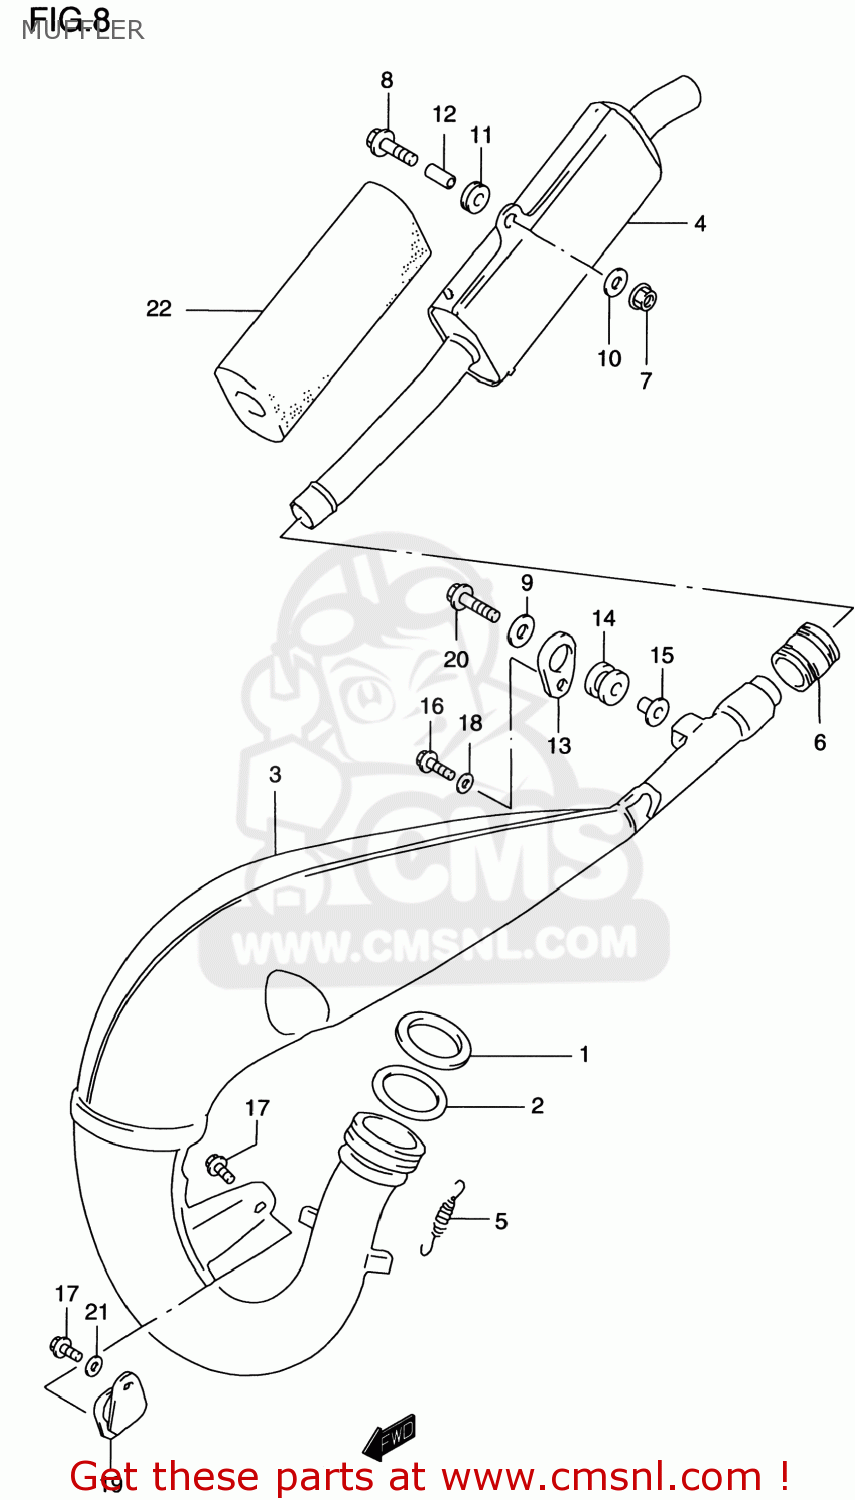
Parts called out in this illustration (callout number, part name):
1	WASHER,EXHAUST PIPE
2	O RING,EXHAUST PIPE
3	BODY,MUFFLER 1ST
4	BODY MUFFL. 2N
5	SPRING
6	CONNECTOR,MUFFLER
7	NUT
8	BOLT,G/S SWITC
9	WASHER(6.5X24X1.2)
10	WASHER(6.5X24X1.2)
11	CUSHION
12	SPACER(6.5X11.5X12)
13	PLATE,MUFFLER MTG
14	CUSHION,MUFFLER
15	SPACER,MUF MTG
16	SCREW
17	BOLT
18	WASHER
19	DAMPER,MUFFLER SUPPORT
20	BOLT
21	WASHER
22	SILENCER,MUFFLER
